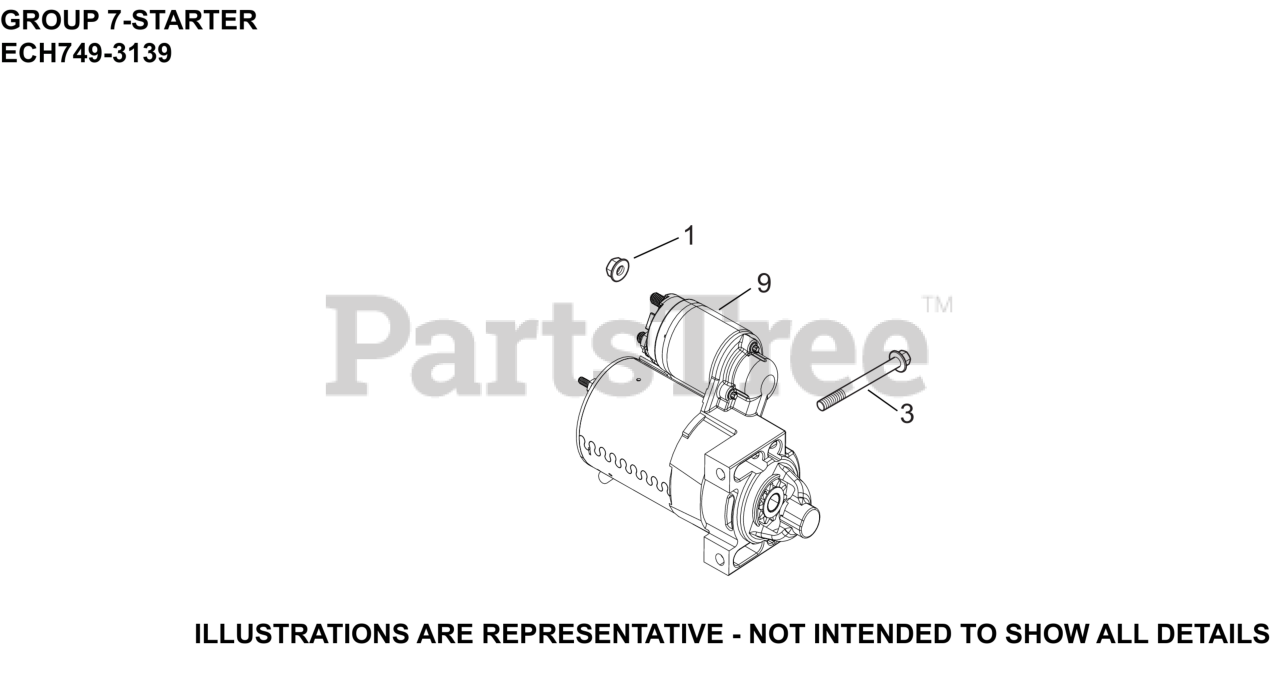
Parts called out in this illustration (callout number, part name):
1	NUT, FLG M8X1.25
3	SCREW, FLG M8X1.25X80
9	STARTER, SOLENOID SHIFT (25 098 09-S)
